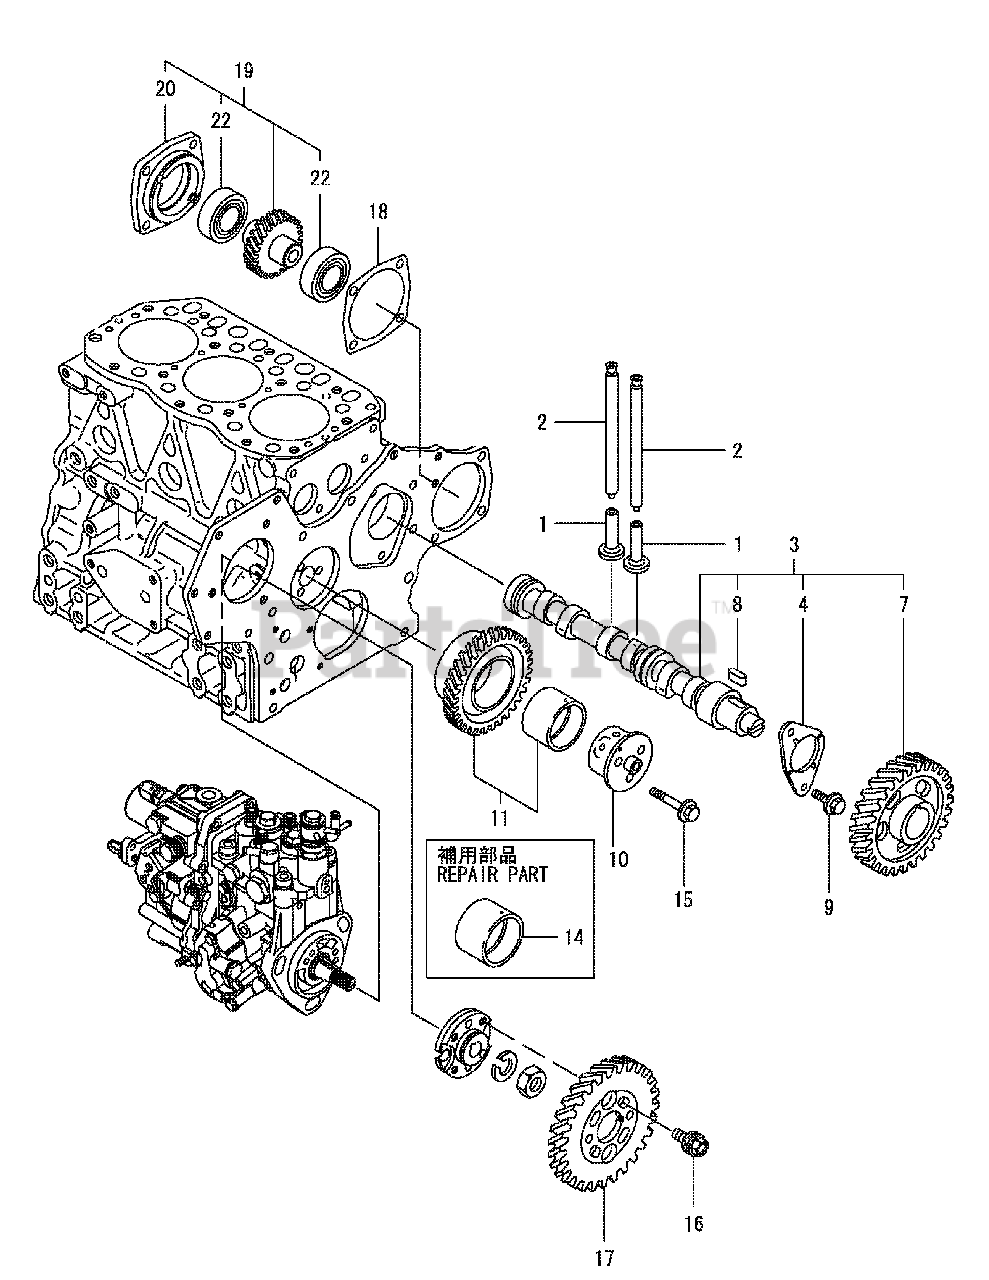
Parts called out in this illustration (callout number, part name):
3	Camshaft Assembly
11	Idle Gear Assembly
14	Idle Gear Bushing
19	Pump Drive Assembly
